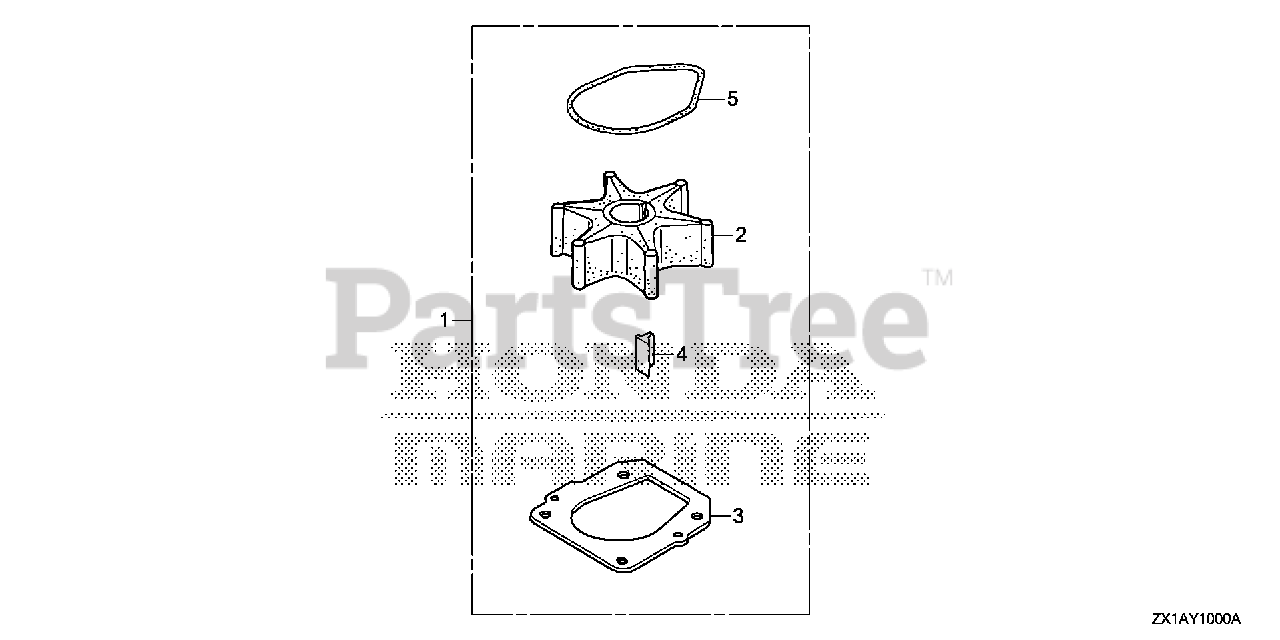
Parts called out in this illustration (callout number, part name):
1	PUMP KIT, IMPELLER
2	IMPELLER, PUMP
3	GASKET B, IMPELLER
4	KEY, WOODRUFF
5	O-RING, WATER PUMP
